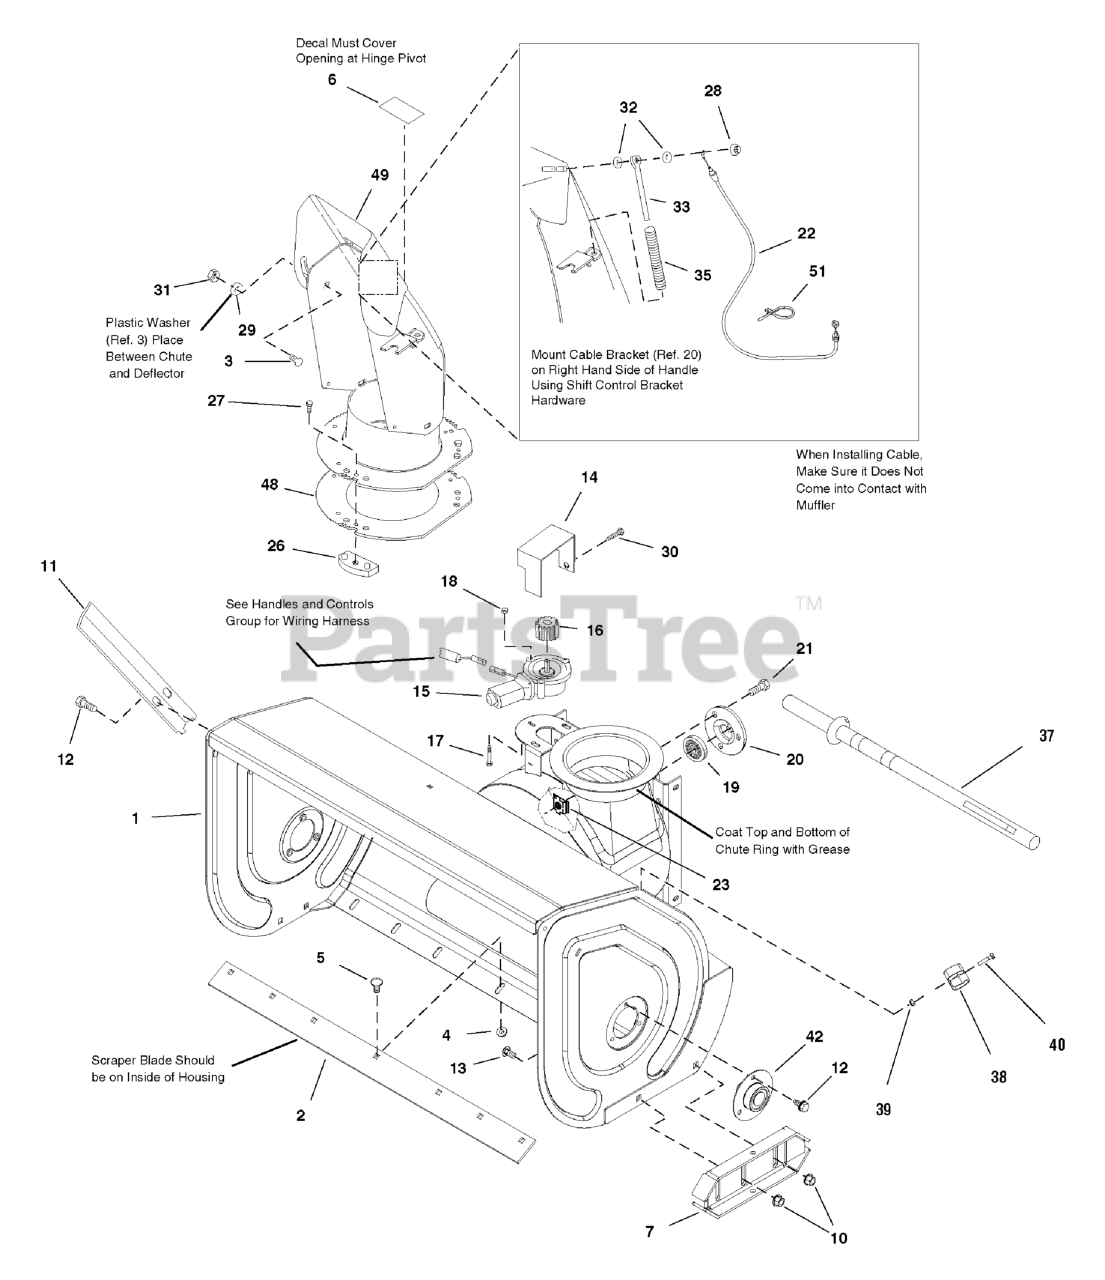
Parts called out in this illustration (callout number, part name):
1	HOUSING ASSEMBLY, 32"
2	BLADE, Scraper for 32"
3	CARRIAGE BOLT, 5/16-18 x 3/4, G5
4	NUT, Hex Flange, 5/16-18 Two-Way Lock
5	CARRIAGE BOLT, 5/16-18 x 5/8, G5
6	DECAL, Green Strip Hinge Snow Chute
7	SKID SHOE
10	NUT, Hex Flange, 3/8-16 ESNA
11	CUTTER, Drift w/Tabs
12	SCREW, Hex Washer Head Taptite, 5/16-18 x 3/4
13	BOLT, Carriage, 3/8-16 x 1
14	COVER, Gear
15	MOTOR, Spout Rotator, 38/42"
16	PINION, 1.417 OD .296 Slot 1-1/4 Long 16T Powdered Metal
17	SCREW, Hex Washer Head Slot, #10C x 1-1/4, G2
18	NUT, Hex Whiz Lock Flange, #10-24
19	BEARING, 3/4 ID x 1.78 OD x .61 Long Greased
20	BEARING RETAINER
21	SCREW, Hex Whiz Lock Flange, 5/16-18 x 3/4
22	CABLE & KNOB ASSEMBLY
23	RETAINER, Nut, 5/16-18 .057/.092
26	HOLD DOWN, Chute, Nylon
27	SCREW, Hex Washer Head Taptite, 10-14 x 5/8
28	NUT, Push
29	WASHER, Nylon, .388 x 1.12 x .03
30	SCREW, Hex Washer Head Taptite, 1/4-20 x 3/8
31	NUT, Hex Flange, 5/16-18 ESNA
33	ROD, Spring
35	SPRING, Compression
37	STICK, Snow Cleanout w/Brush, Plastic
38	CLIP, Retainer
39	NUT, Hex Lock, 10-24 w/Nylon Insert
40	SCREW, Truss-Head TORX, #10-24 x 3/8
42	BEARING, Ball
48	GEAR, Chute, 10 OD 6.65 ID .105 Thick
49	CHUTE ASSEMBLY, with Pigtail Green
51	TIE, Self Locking, .184 Wide 7.31 Long
